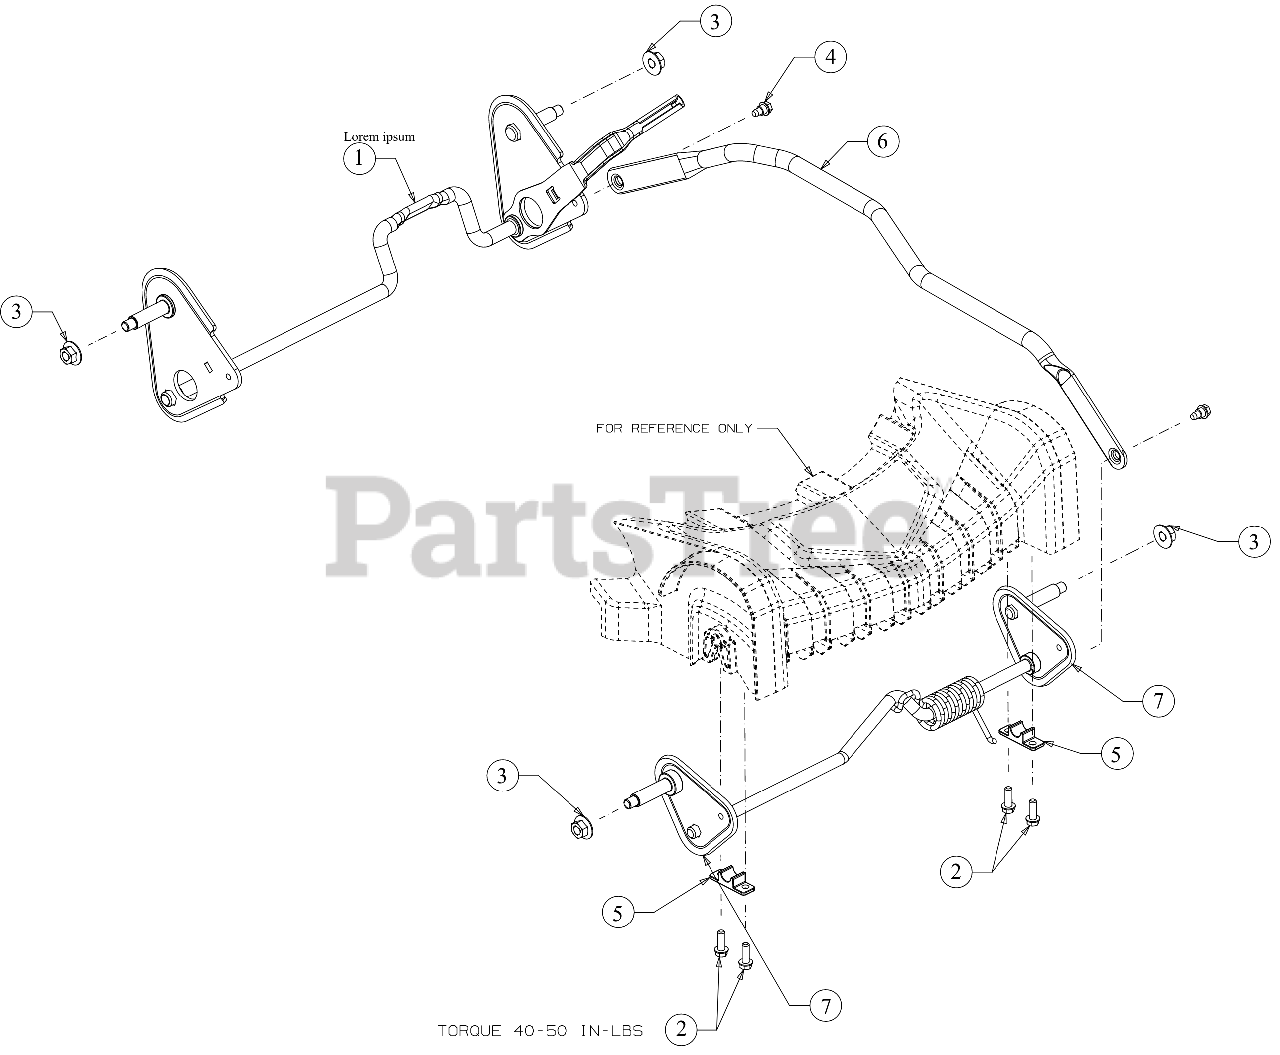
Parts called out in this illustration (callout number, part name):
1	HEIGHT AXLE ASSEMBLY
2	SCREW 1/4-15 X .750
3	FLANGE LOCK NUT
4	SHOULDER SCREW 1/4-20 X .50
5	BLOCK BUSHING
7	FRONT AXLE ASSEMBLY
